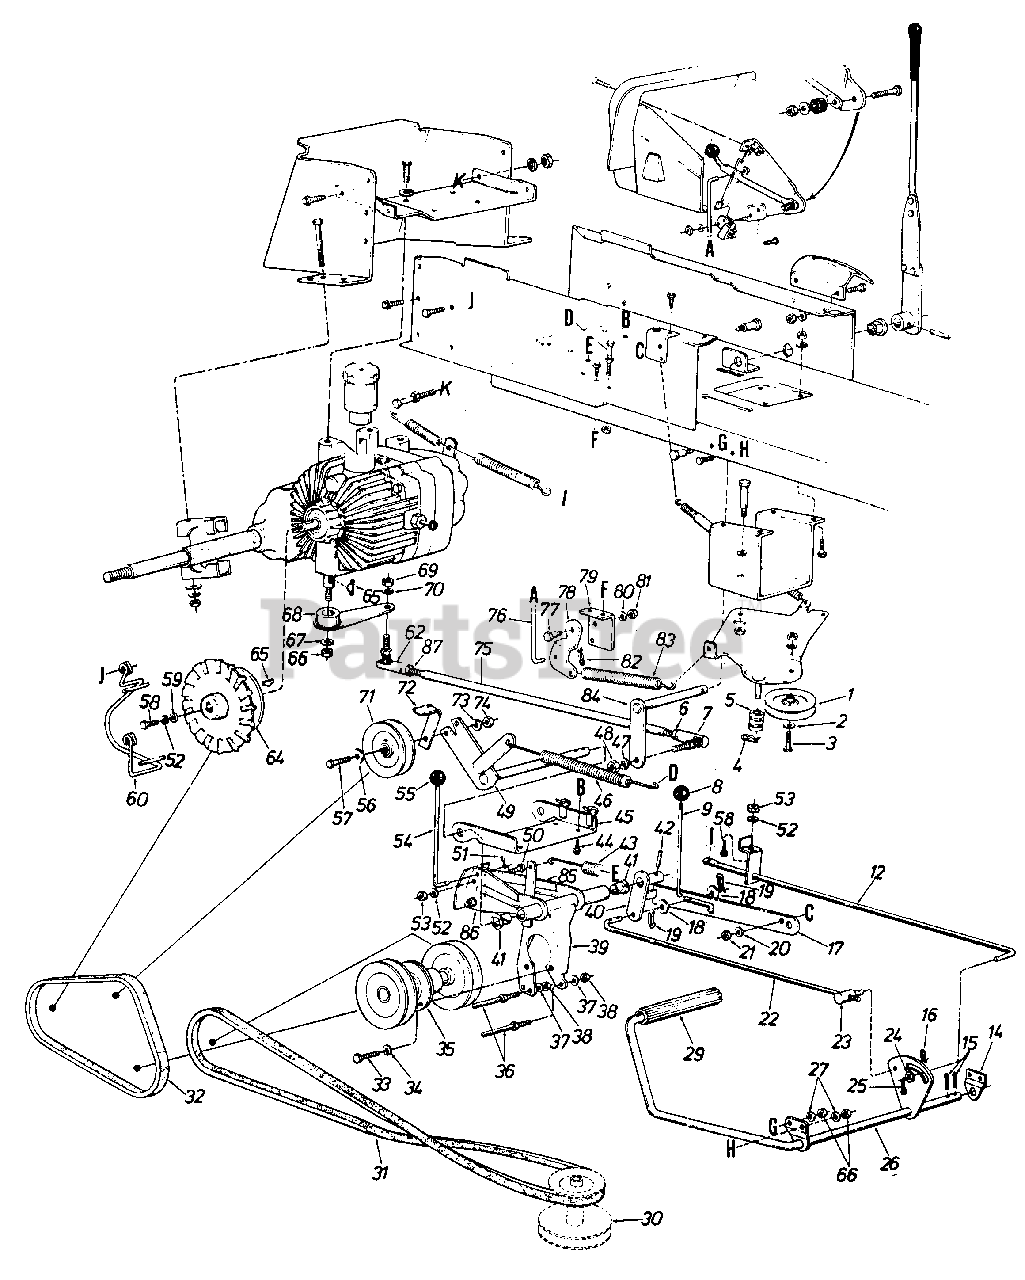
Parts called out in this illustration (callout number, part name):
1	4" Dia. 'V"-ldler Pulley
2	F I-Was h . 3/8 " 1. D .
3	Hex Bolt 3/8-16 x 1.25" Lg.*
4	Intern. Cotter Pin 5/16" Dia.
5	Spacer
6	Hex Jam L-Nut 3/8-24 Thd.
7	Ball Joint Ass'y. 3/8-24 Thd.
8	Ball Knob
9	Parking Brake Link
9	Brake Rod Hanger
12	Brake Rod
14	Clutch Rod Brg. Brkt.
15	Cotter Pin 1/8" Dia. x 1.00" Lg.*
16	Hairpin Cotter 1/2" Dia.
17	Parking Brake Cam
18	Fl-Wash. .406 I.D. x 1.00" O.D. x .030
19	Hairpin Cotter 1/2" Dia.
20	Fl-Wash. 5/16" Scr.*
21	Hex Nut 5/16-18 Thd.*
22	Brake Cam Rod
23	Pivot Bushing
24	Fl-Wash. .401" I.D. x .749" O.D. x .057" Thk.
25	Cotter Pin 1/8" Dia. x 1.00" Lg.
26	Clutch Brake Pedal Ass'y.
27	L-Wash. 3/8" I.D.
29	Foot Pad
30	Two-Step Engine Pulley 4.75" and 5.56"
31	V-Belt 1/2" x 59" Lg.
32	V-Belt 1/2" x 37" Lg.
33	Hex Sems Bolt 5/16-18 x .75" Lg.*
34	L-Wash. 5/16" I.D.*
35	Jack Shaft Ass'y.
36	Stud 3/8-16 x 3.62" Lg.
37	L-Wash. 3/8" I.D.*
38	Hex Nut 3/8-16 Thd.*
39	Jack Shaft Mtg. Brkt. Ass'y.
40	Clutch Idler Horn Ass'y.
41	Nyliner 5/8" I.D. x .88" Lg.
42	Spring Pin Spiral 1/4" Dia. x 1.5" Lg.
43	Ext. Spring (Jack Shaft)
44	Hex Wash. Hd. Self-Tap Scr. 1/4-20 x .50" Lg.
45	Idler Mtg. Brkt.
46	Ext. Spring (Drive Idler)
47	L-Wash. 3/8" I.D.*
48	Hex Nut 3/8-24 Thd.*
49	Clutch Brkt. Ass'y.
50	Hex Bolt 1/4-20 x .50" Lg.*
51	Internal Cotter Pin 5/16" Dia. Rod
52	L-Wash. 1/4" I.D.*
53	Hex Nut 1/4-20 Thd.*
54	Relief Valve Lockout Rod
55	Ball Knob
56	Fl-Wash. 3/8" I.D.
57	Hex Bolt 3/8-16 x 1.25" Lg.*
58	Hex Bolt 1/4-20 x .62" Lg.*
59	Fl-Washer
60	Belt Guard Ass'y.
62	Ball Joint Ass'y. 3/8-24 0 L.H. Thd.
64	Transaxle Pulley w/ Fan
65	Hi-Pro Key 1/8" x 1/2" Dia.
66	Hex Nut 3/8-16 Thd.*
67	L-Wash. 3/8" I.D.*
68	Pintle Arm Ass'y.
69	Hex Nut 3/8-24 Thd.*
70	L-Wash. 3/8" I.D.*
71	4" "V"-ldler Pulley
74	Hex Nut 3/8-16 Thd.*
75	Speed Control Rod
76	Deck Control Rod
77	Shld. Scr. .437" Dia. x .162" Lg. (5/16-18)
78	Deck Control Pivot Brkt.
79	Parking Brake Cam Mtg. Brkt.
80	L-Wash. 5/16" I.D.*
81	Hex Nut 5/16-18 Thd.*
82	Internal Cotter Pin 5/16" Rod
83	Extension Spring
84	Speed Control Shaft Ass'y.
85	Relief Valve Cam L.H.
86	Relief Valve Cam R.H.
87	Hex Jam L-Nut 3/8-24 L.H. Thd.*
